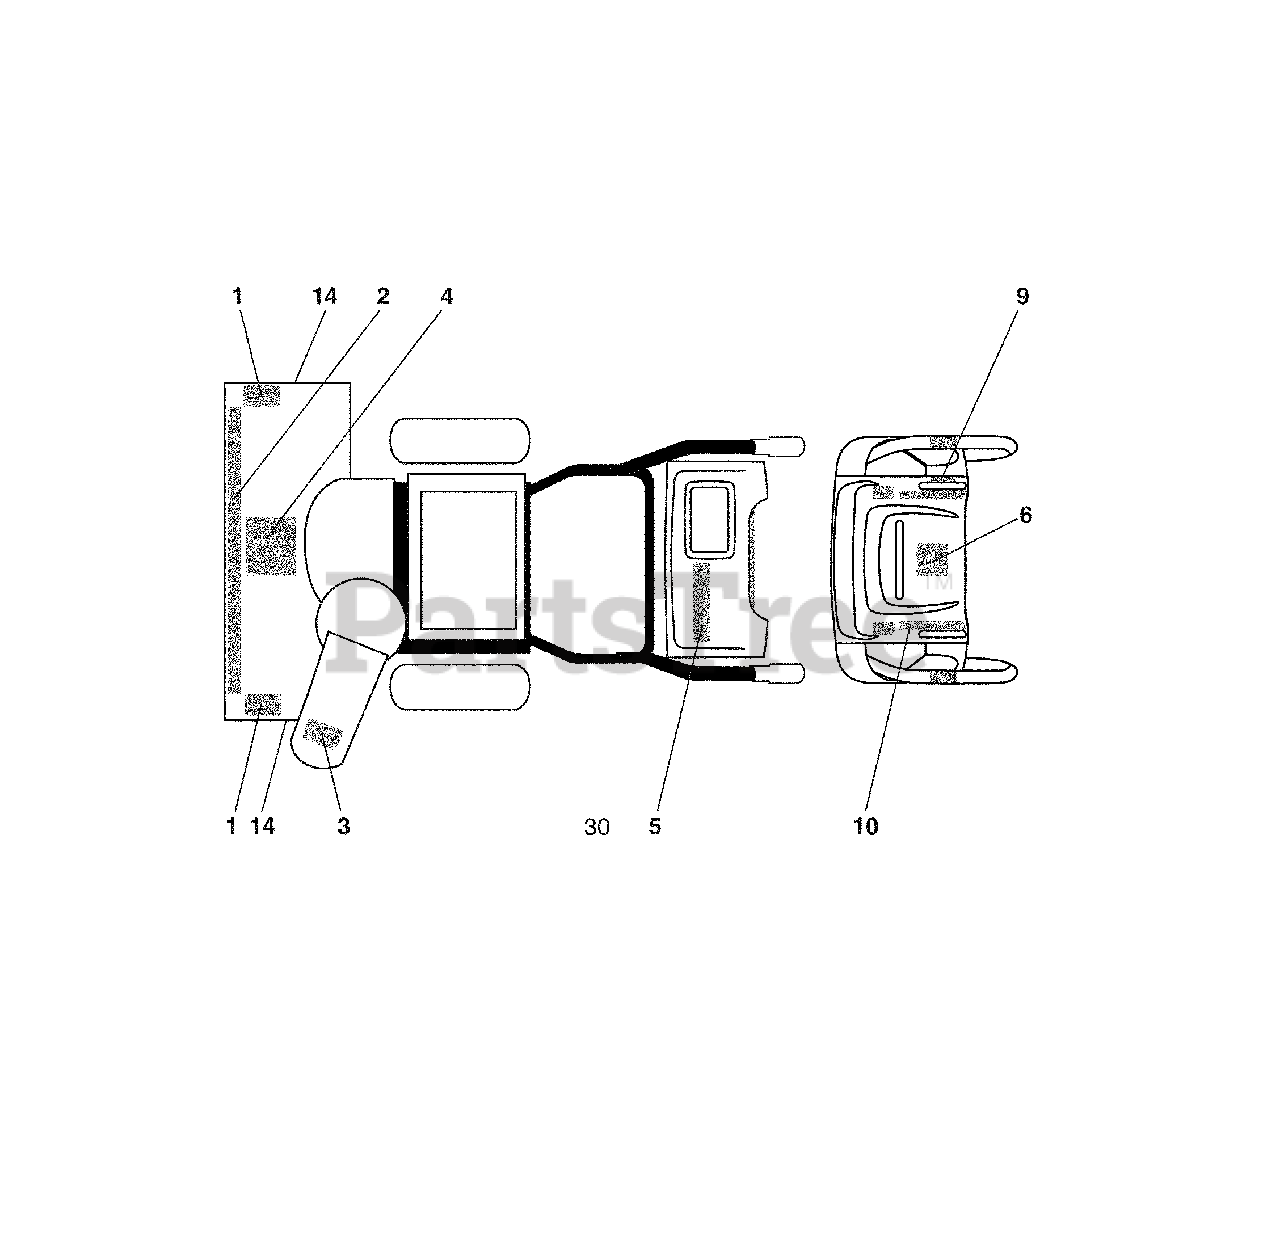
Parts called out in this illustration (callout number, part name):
1	Decal, Danger
2	Decal, Husqvarna
3	Decal, Danger, Deflector
4	Decal, Danger
5	Decal, Husqvarna, 1130SBE-OV
6	Decal, Instruction
9	Decal, Speed Control
10	Decal, Remote Deflector
11	Decal, LH Trigger
12	Decal, RH Trigger
14	Decal, Husqvarna, Crown
